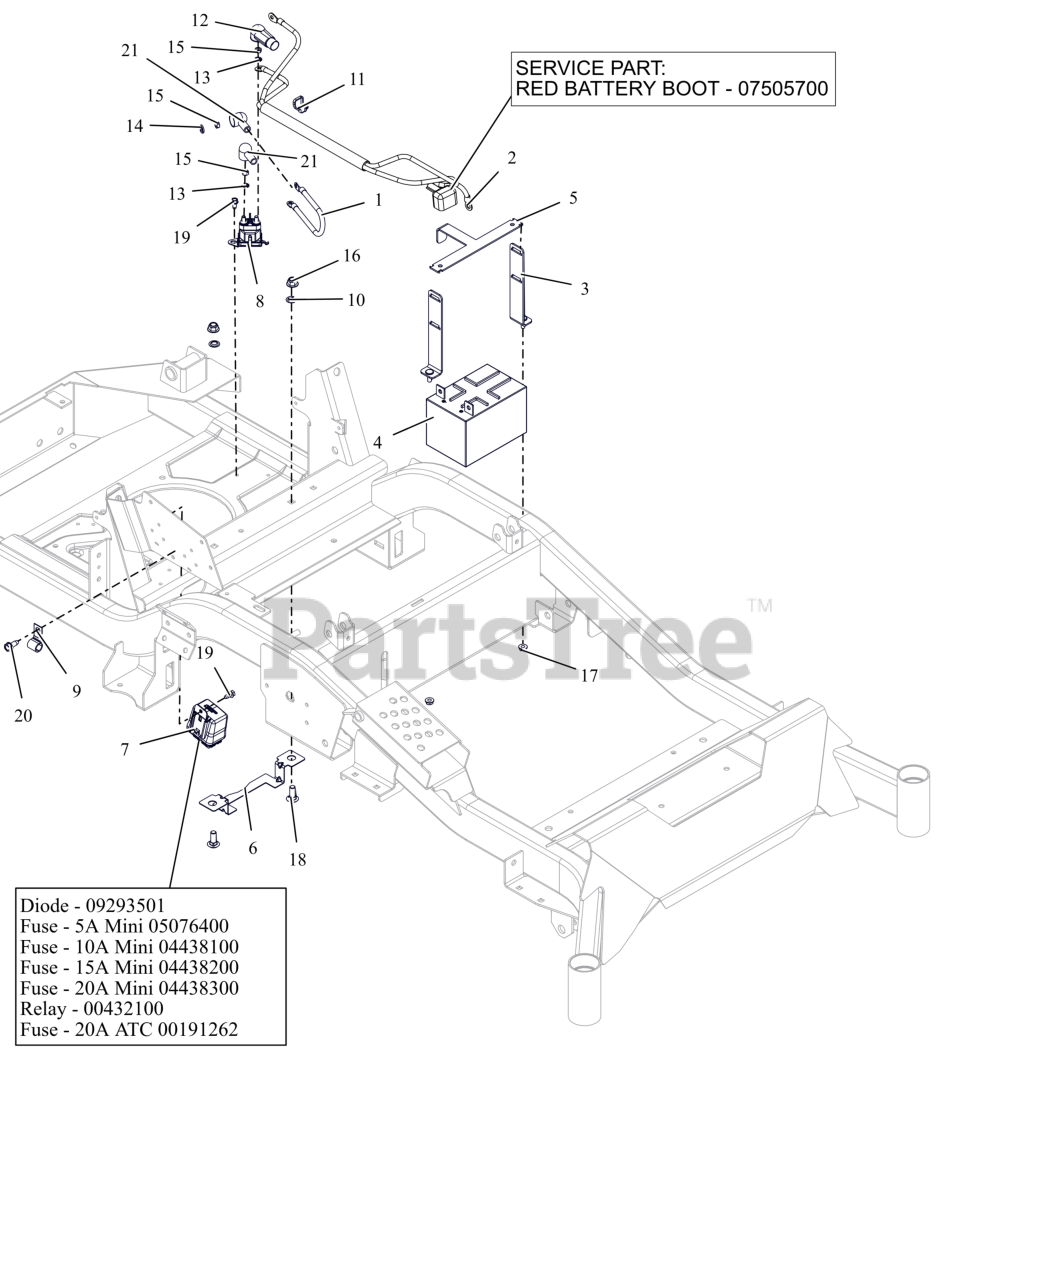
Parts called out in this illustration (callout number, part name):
1	CABLE, POS W/(2)1/4 RING 9.0LG
2	HARNESS, BATTERY HD
2	INSULATOR
3	WMT,BATTERY MOUNT HOLD DOWN
4	BATTERY, 12V 12A-190CCA
5	BRKT, BATTERY TIE DOWN
6	GUARD, ELECTRICAL HARNESS
7	HARNESS, WIRE
7	DIODE, CONNECTOR SHELL
7	RELAY,MICRO5 TERML W/RESISTOR
7	FUSE, 5 AMP MINI-ATC
7	FUSE,10 AMP MINI-ATC
7	Fuse, 15 AMP MINI-ATC
7	FUSE,20 AMP MINI ATC
7	FUSE, 20 AMP BLADE S/O
8	SOLENOID, STARTER (SEALED)
9	J-CLAMP
10	NUT-PUSH .38 DIA. PAL ZINC
11	CABLE TIE W/ TREE (.25 HOLE)
12	BOOT, .65ID POS
13	WSHR,LK-EXT.262X.502X.026 ZCC
14	WSHR,LK-REG .312X.078 ZCC
15	NUT-STD M6-1.0 ZCC
16	NUT,NYL-FLG .38-16 GF ZCC
17	NUT-LK-TOP-FLG .250-20 GF ZCC
18	BLT, RHSN .38-16X1.00 G5 ZCC
19	SCR-TAP .25-20X.50 HWH ZCC
20	SCR,TAP .312-18X.75 HWH TR ZCC
21	BOOT, EYELET TERMINAL
